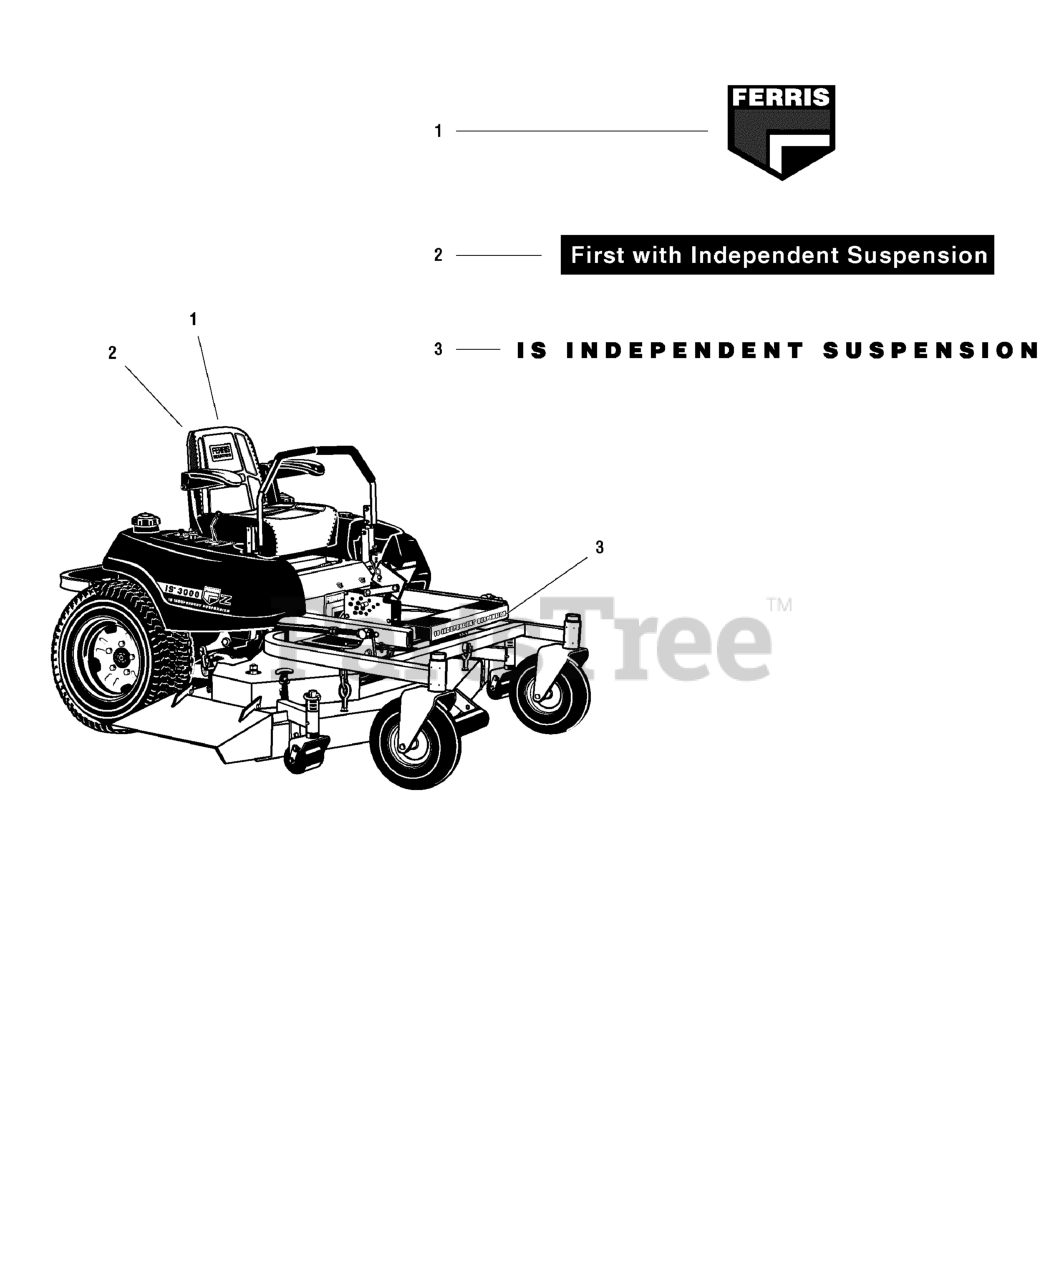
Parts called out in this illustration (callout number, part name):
1	DECAL, Ferris Logo, 6-3/8"
2	DECAL, First w/ Independent Suspension
3	DECAL, IS Independent Suspension
